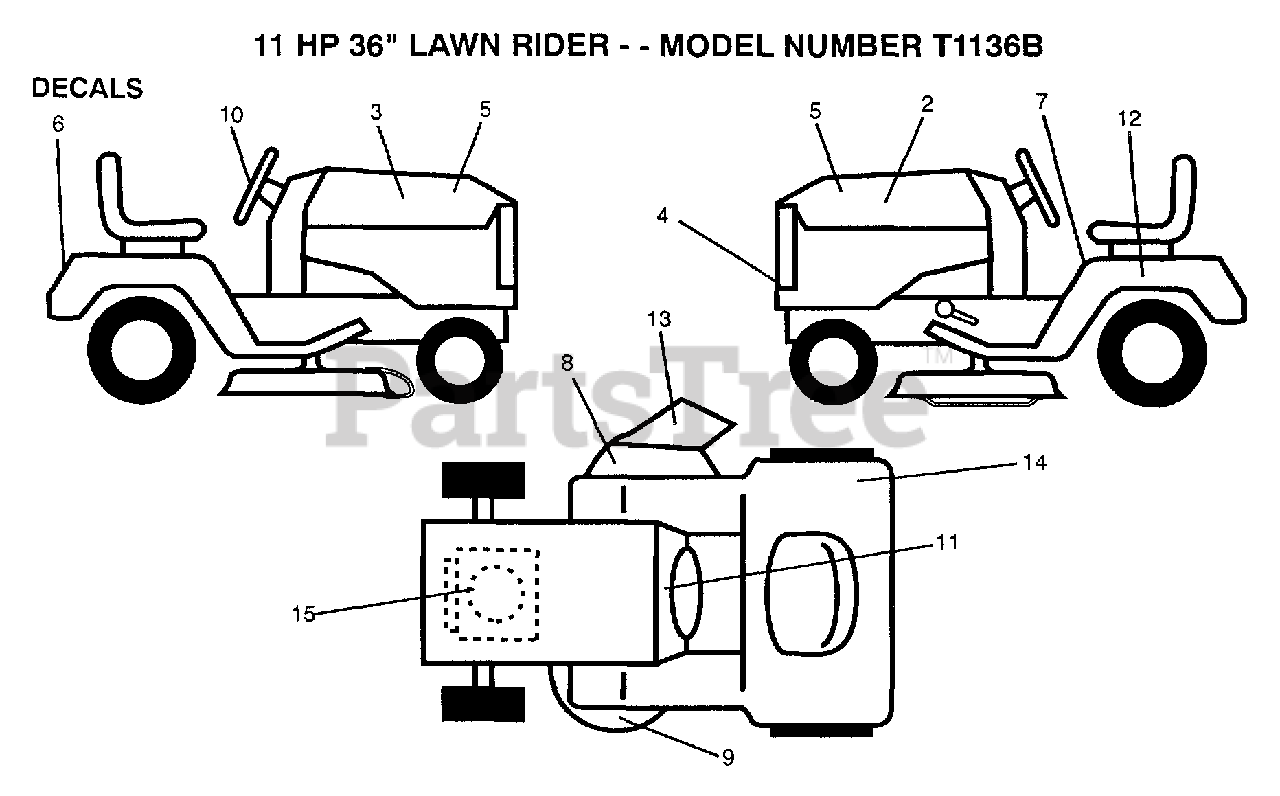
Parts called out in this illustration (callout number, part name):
2	DECAL, HOOD, L.H.
3	DECAL, HOOD, R.H.
4	"DECAL,GRILL"
6	FENDER DECAL
7	DECAL
8	DECAL WARNING
9	DECAL YT
10	"DECAL,STR WHL T"
12	DECAL
13	DECAL WARNING
15	DECAL.ENG.27164
